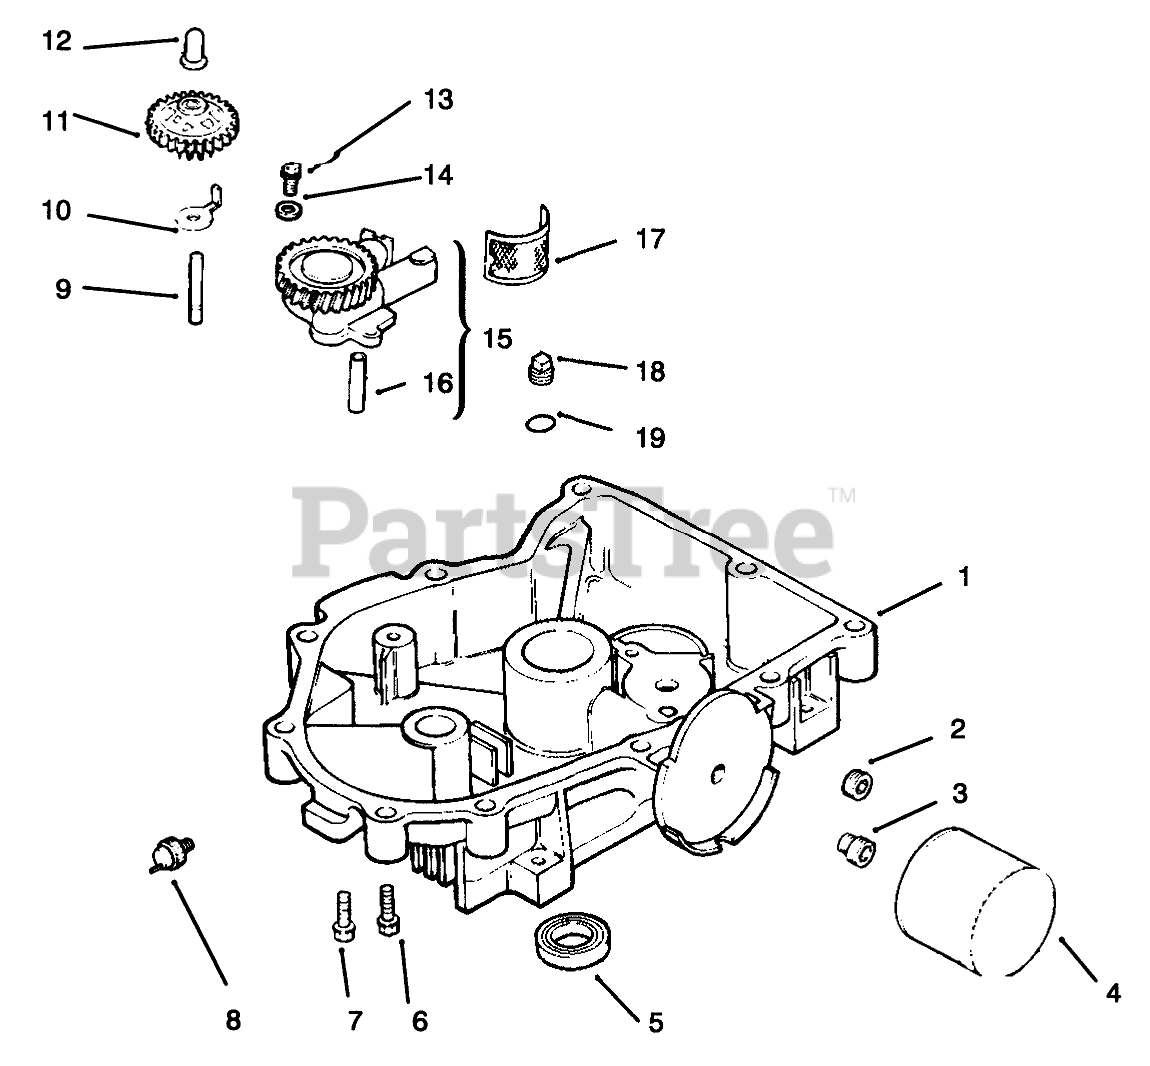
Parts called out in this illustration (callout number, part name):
1	Oil Pan
2	Plug-Hex
3	Nipple-Filter, Oil
4	Filter-Oil
5	Seal-Oil
6	Screw
7	Screw
8	Switch, pressure
9	Shaft-Gear, Governor
10	Tab-Locking
11	Governor Gear ASM
12	Pin-Governor
13	Screw
14	Washer
15	Oil Pump ASM INC 16
16	Tube-Oil Pickup
17	Screen-Oil Pickup
18	Plug
19	O Ring
